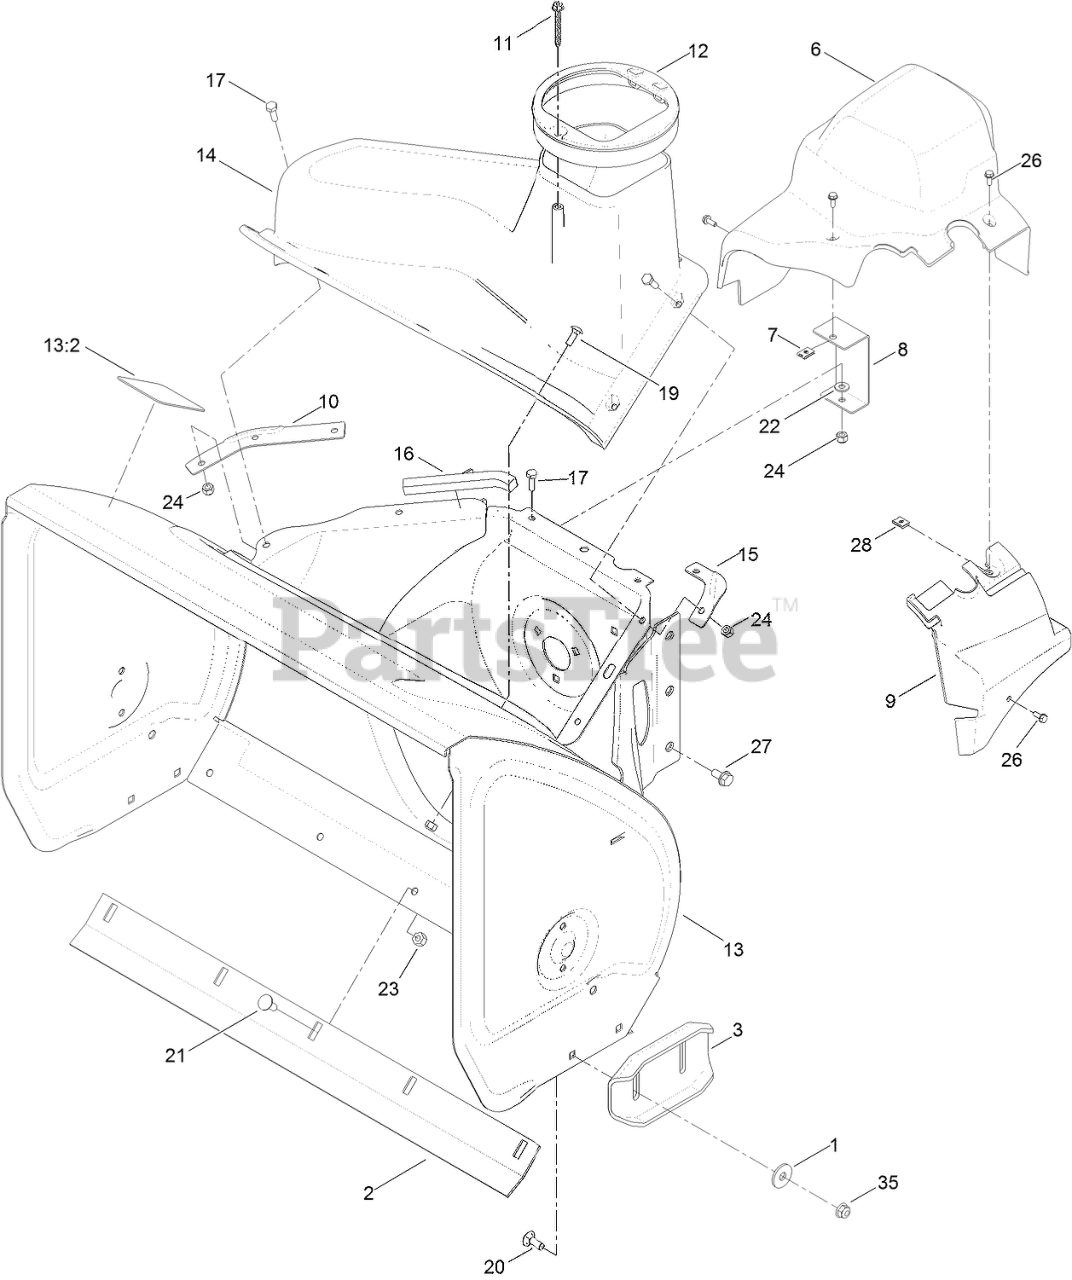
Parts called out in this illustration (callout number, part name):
1	WASHER
2	SCRAPER-FIXED
6	COVER-BELT
7	NUT-SPEED, U-TYPE
8	BRACKET-COVER, CLIP NUT
9	COVER-EXTENSION, BELT
10	SEAL-FLANGE, COVER
11	SCREW-HWH, PLASTITE
12	GUIDE-CHUTE
13	HOUSING-AUGER, 28 INCH
13:2	DECAL-DANGER, AUGER
16	SEAL-HOUSING
17	SCREW-HH
19	BOLT-CARR
20	SCREW-CARR
21	SCREW-CARR
22	WASHER-FLAT
23	NUT-LOCK, NI
24	NUT-LOCK, NI
26	SCREW-HWH
27	SCREW-HWHTF
28	NUT-SPEED
35	NUT-HF, NI
